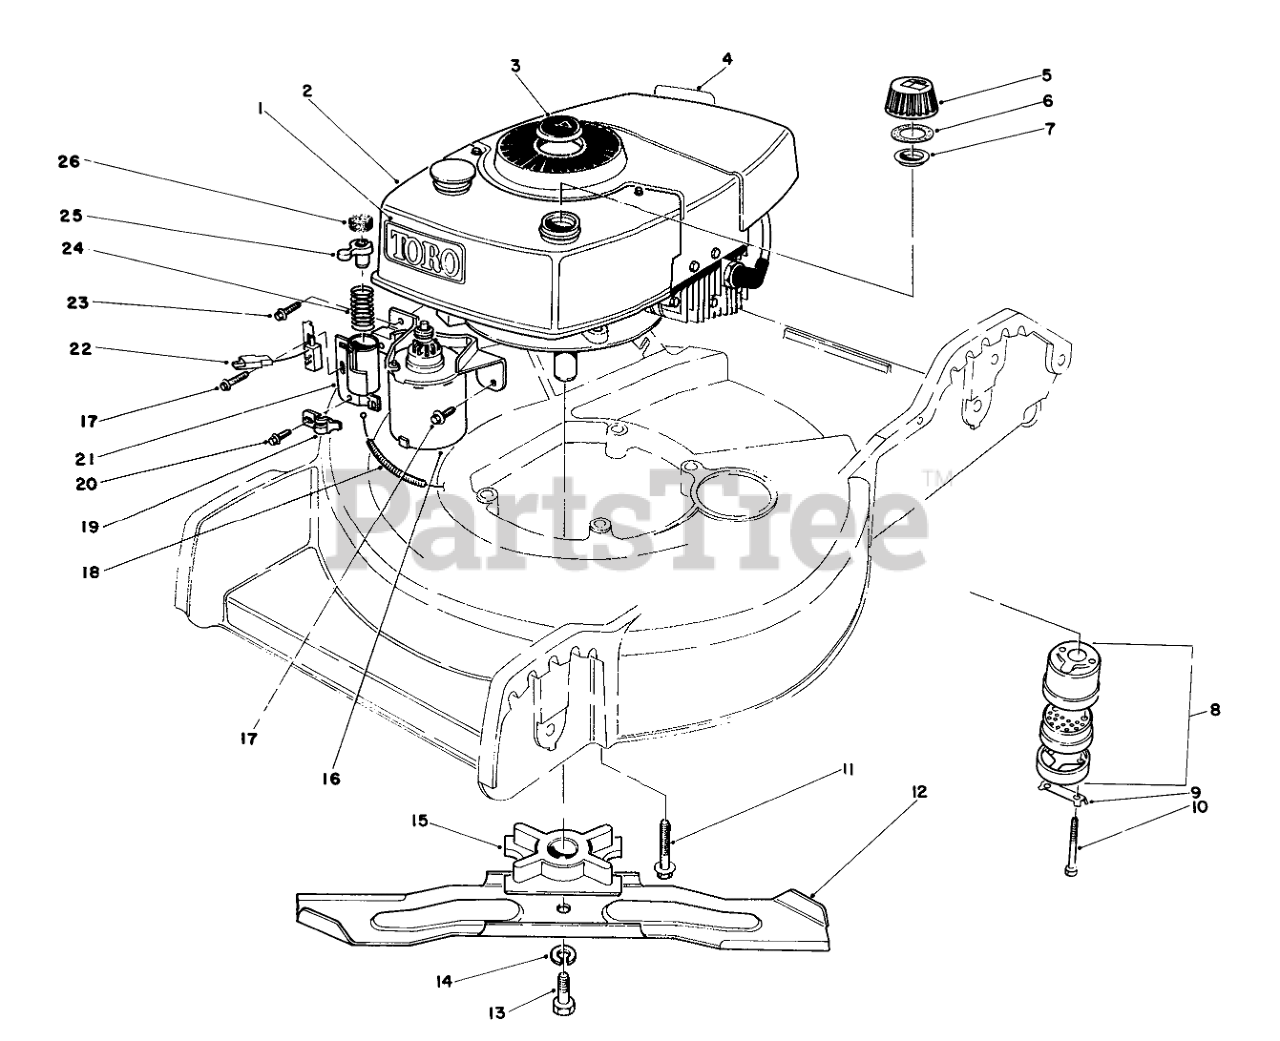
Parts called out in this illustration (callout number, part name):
1	Spring
3	PLUG BUTTON
4	Decal-Maintenan
5	Gas Cap Assembly (Incl. Ref. #6 & 7)
6	GASKET
7	GAS CAP BAFFLE
8	Muffler Assembly (Incl. Ref. #9 & 10)
9	CLIP - LOCKING
10	SCREW-HH
11	3/8-16 X 2 CAPSCREW
12	Blade
13	SPECIAL SCREW
14	WASHER-LOCK
15	BLADE RETAINER
16	STARTER MOTOR ASM
17	SCREW
18	BRAKE CABLE-SUZUKI
19	CABLE CLAMP
20	SCREW
21	TUBE W A
22	PUSH BUTTON SWITCH
23	Screw
24	COMPRESSION SPRING
25	Plunger
26	Pad-Friction
